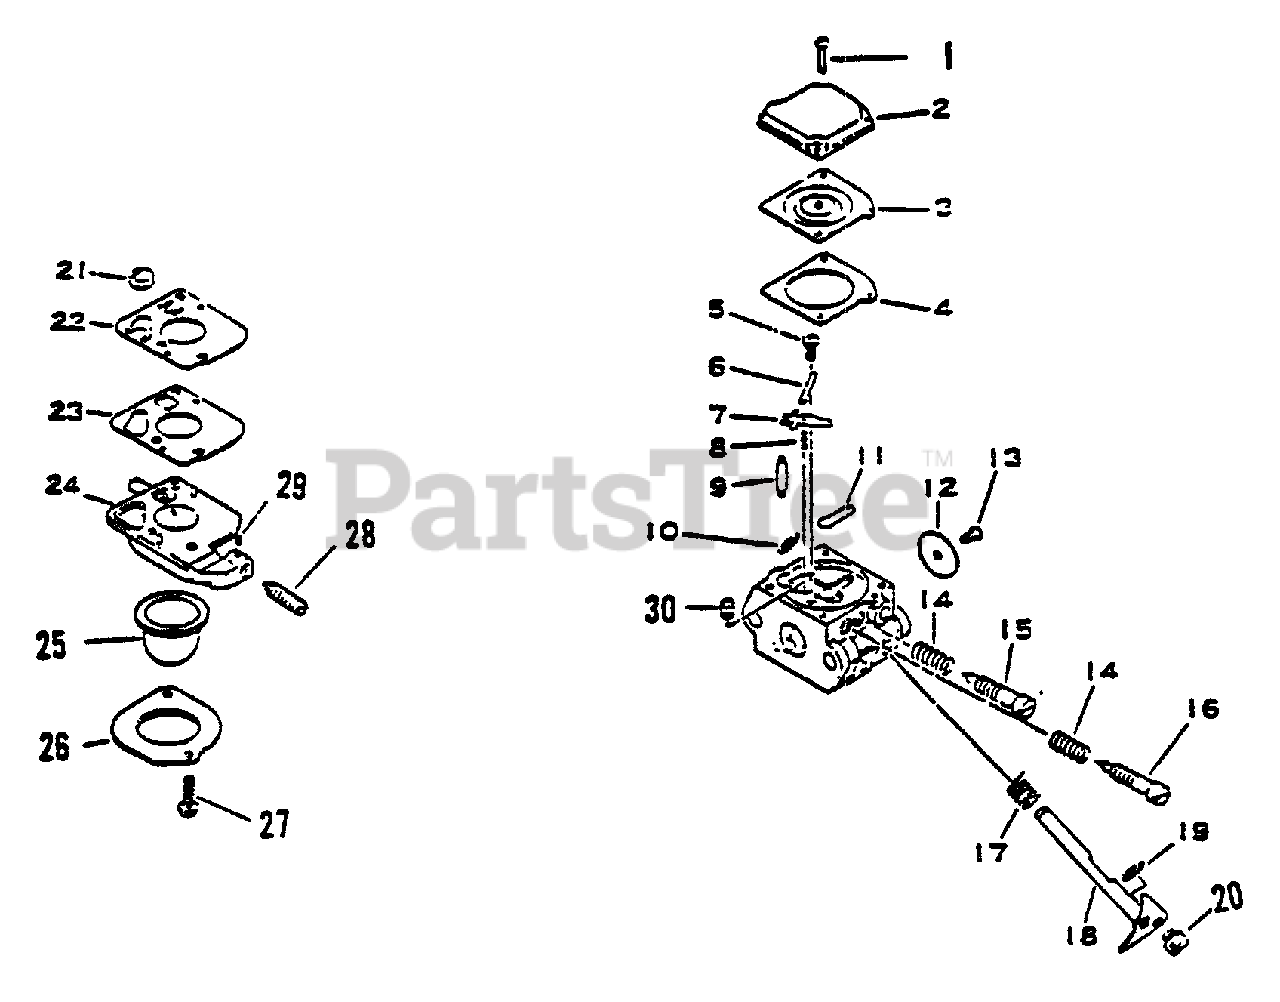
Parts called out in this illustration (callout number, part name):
2	COVER, METERING
3	DIAPHRAGM
4	GASKET, METERING
5	SCREW
6	PIN
7	LEVER, METERING
8	SPRING
9	VALVE, NEEDLE
10	RING, RETAINING
11	PLUG, WELCH
12	VALVE, THROTTLE
15	NEEDLE - HIGH SPEED
16	NEEDLE - LOW SPEED
17	SPRING, RETURN
18	SHAFT, THROTTLE
19	RING, RETAINING
21	STRAINER
22	DIAPHRAGM, PUMP
23	GASKET, PURGE
24	COVER, PUMP
25	BULB, PURGE
26	RETAINER, PURGE BULB
27	SCREW, RETAINER
28	SCREW, IDLE ADJUST
29	PIECE, FRICTION
30	NOZZLE, CHECK VALVE
